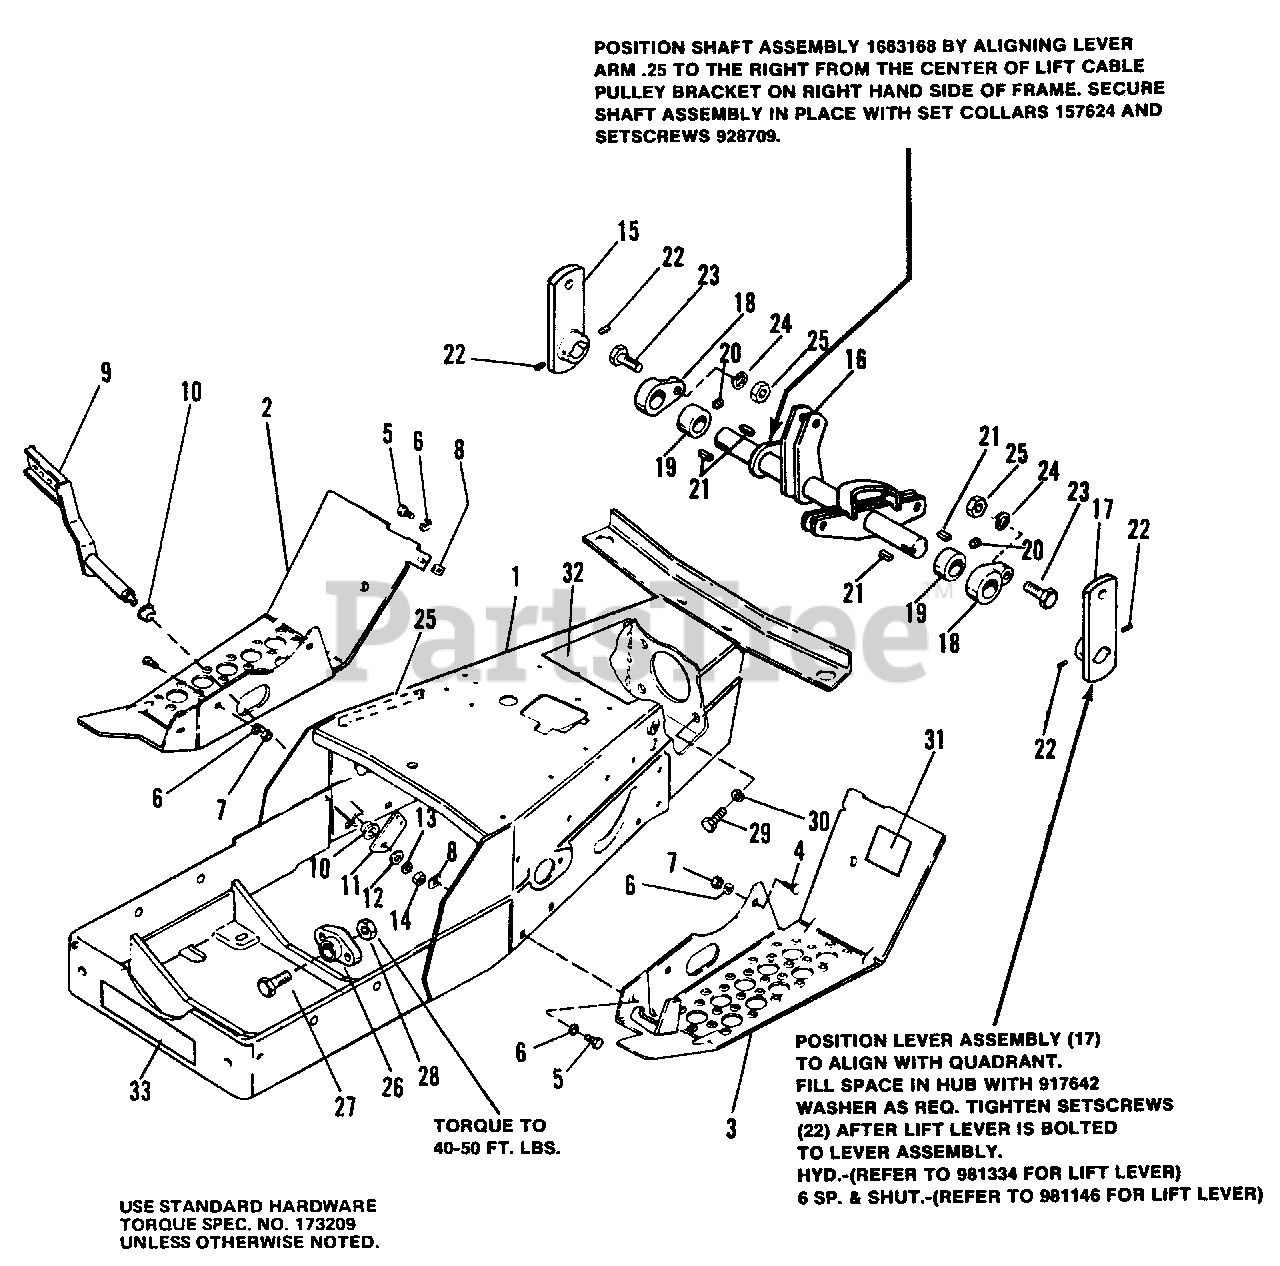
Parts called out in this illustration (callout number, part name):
1	REAR FRAME ASSEMBLY
2	FOOT REST, R.H.
3	FOOT REST, L.H.
4	BOLT, Carriage, 5/16-18 x 3/4
5	CAPSCREW, Hex Hd., 5/16-18 x 3/4
6	LOCKWASHER, 5/16
7	NUT, Hex, Full, 5/16-18
8	NUT, Speed, Tinn., 5/16-18
9	FOOT PEDAL ASSEMBLY
11	ARM, Pedal Foot
12	WASHER, 3/8
13	LOCKWASHER, 3/8
14	NUT, Hex, Full, 3/8-16
15	FRONT LIFT LEVER ASSEMBLY
16	LIFT SHAFT ASSEMBLY
17	LIFT LEVER ASSEMBLY
18	BEARING, Lift Lever
19	SET, Collar
20	SETSCREW, Cup Pt., 5/16-18 x 3/8
22	SETSCREW, Soc. Hd., 5/16-18 x 1/4
23	CAPSCREW, Hex Hd., 5/16-18 x 1-1/4
24	LOCKWASHER, 5/16
25	DECAL, Clutch
26	BEARING, Pivot
27	CAPSCREW, Whiz, 3/8-16 x 1-1/4
28	NUT, Flange, 3/8-16
29	CAPSCREW, Hex Hd., 7/16-14 x 1-1/2
30	LOCKWASHER, 7/16
31	DECAL, Parking Brake
32	DECAL, Shift Pattern
33	DECAL, Simplicity
